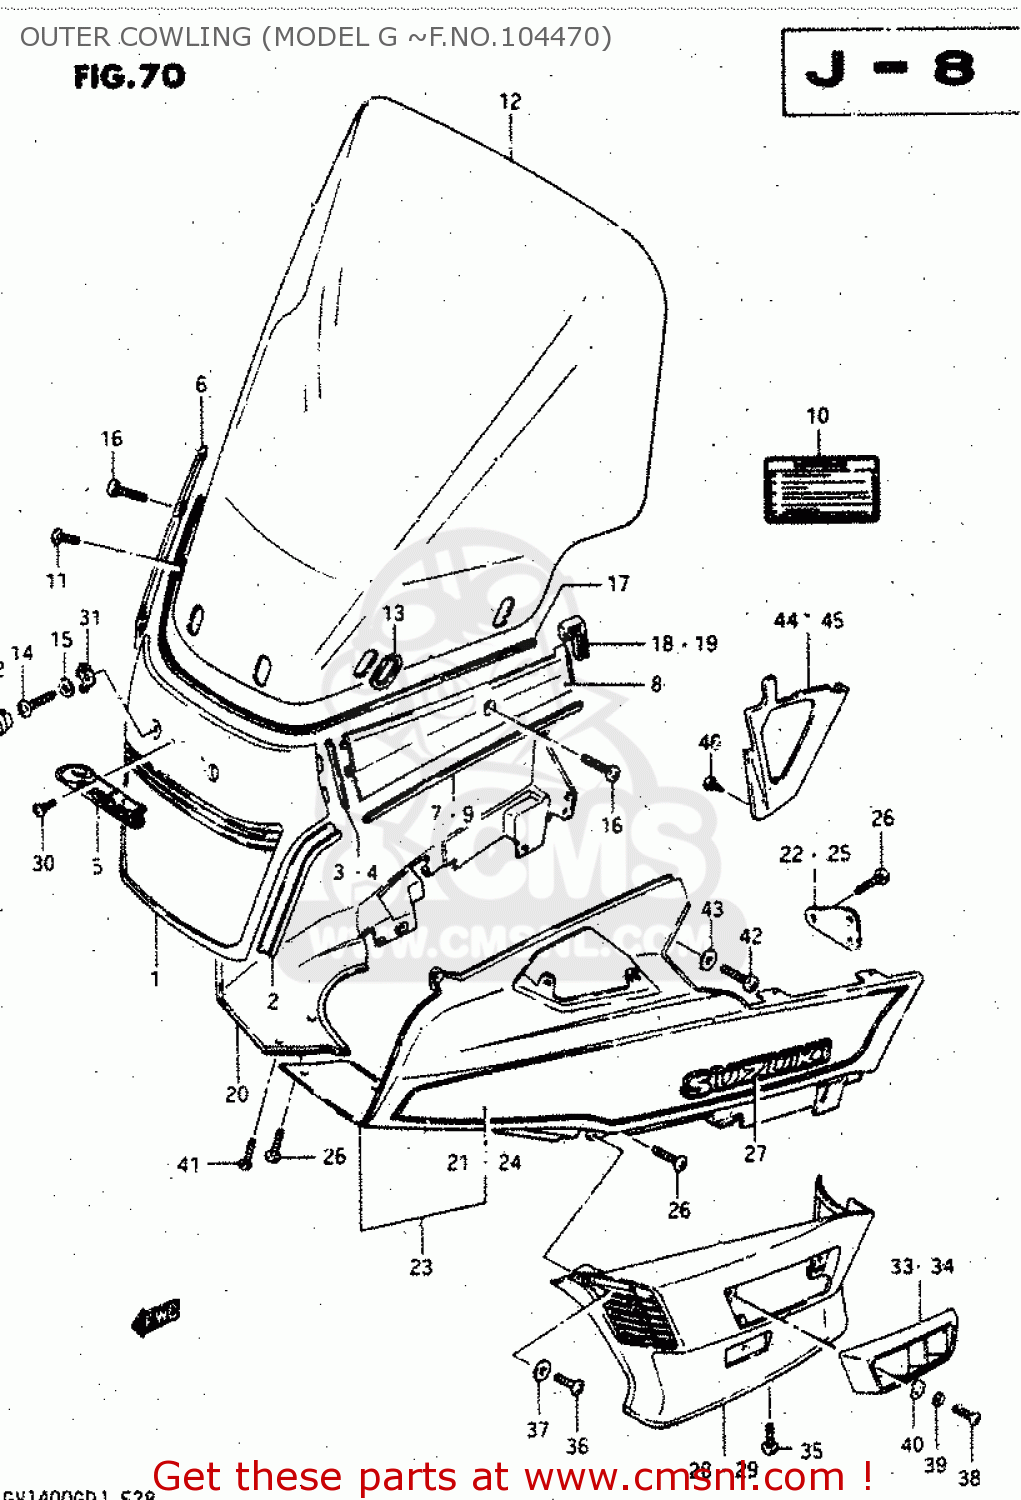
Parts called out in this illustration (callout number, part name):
1	COVER,COWLING,FRONT,CENTER
2	MOLDING,FRONT COVER,LOWER
3	CUSHION,WINDSHEILD
4	PLATE,WINDSHEILD
5	EMBLEM,COWLING,FRONT
6	COVER,COWLING,FRONT,RIGHT
7	MOLDING,FRONT COVER SIDE
8	COVER,COWLING,FRONT,LEFT
9	MOLDING,FRONT COVER SIDE
10	LABEL (WARNING SCREEN)
11	SCREW
12	SCREEN ASSEMBLY,COWLING
13	WASHER,SCREEN
14	SCREW
15	WASHER
16	SCREW
17	SEAL,FRONT COVER,CENTER
18	CAP,COWLING FRONT COVER END
19	CAP,COWL FR COVER END,L
20	BODY,COWLING,RIGHT
21	TAPE SET,COWLING BODY
22	BRACKET,COWLING BODY,RIGHT
23	BODY,COWLING,LEFT
24	TAPE SET,COWLING
25	BRACKET,COWLING BODY,RIGHT
26	SCREW
27	EMBLEM,COWLING SIDE,LEFT
28	COVER ASSEMBLY,COWLING
29	COVER ASSEMBLY,COWLING SIDE,LEFT
30	SCREW
31	PLATE,FR COVER LOCK
32	CAP,FR COVER
33	LOUVER,SIDE COVER,RIGHT
34	LOUVER,SIDE COVER,LEFT
35	SCREW (M6X1X16)
36	SCREW
37	WASHER (4.3X13X0.80)
38	SCREW 4X16
39	LOCK WASHER
40	WASHER
41	SCREW
42	SCREW
43	WASHER
44	UNDER COVER, FRAME
45	COVER,COVER FRAME,UPPER
46	SCREW
